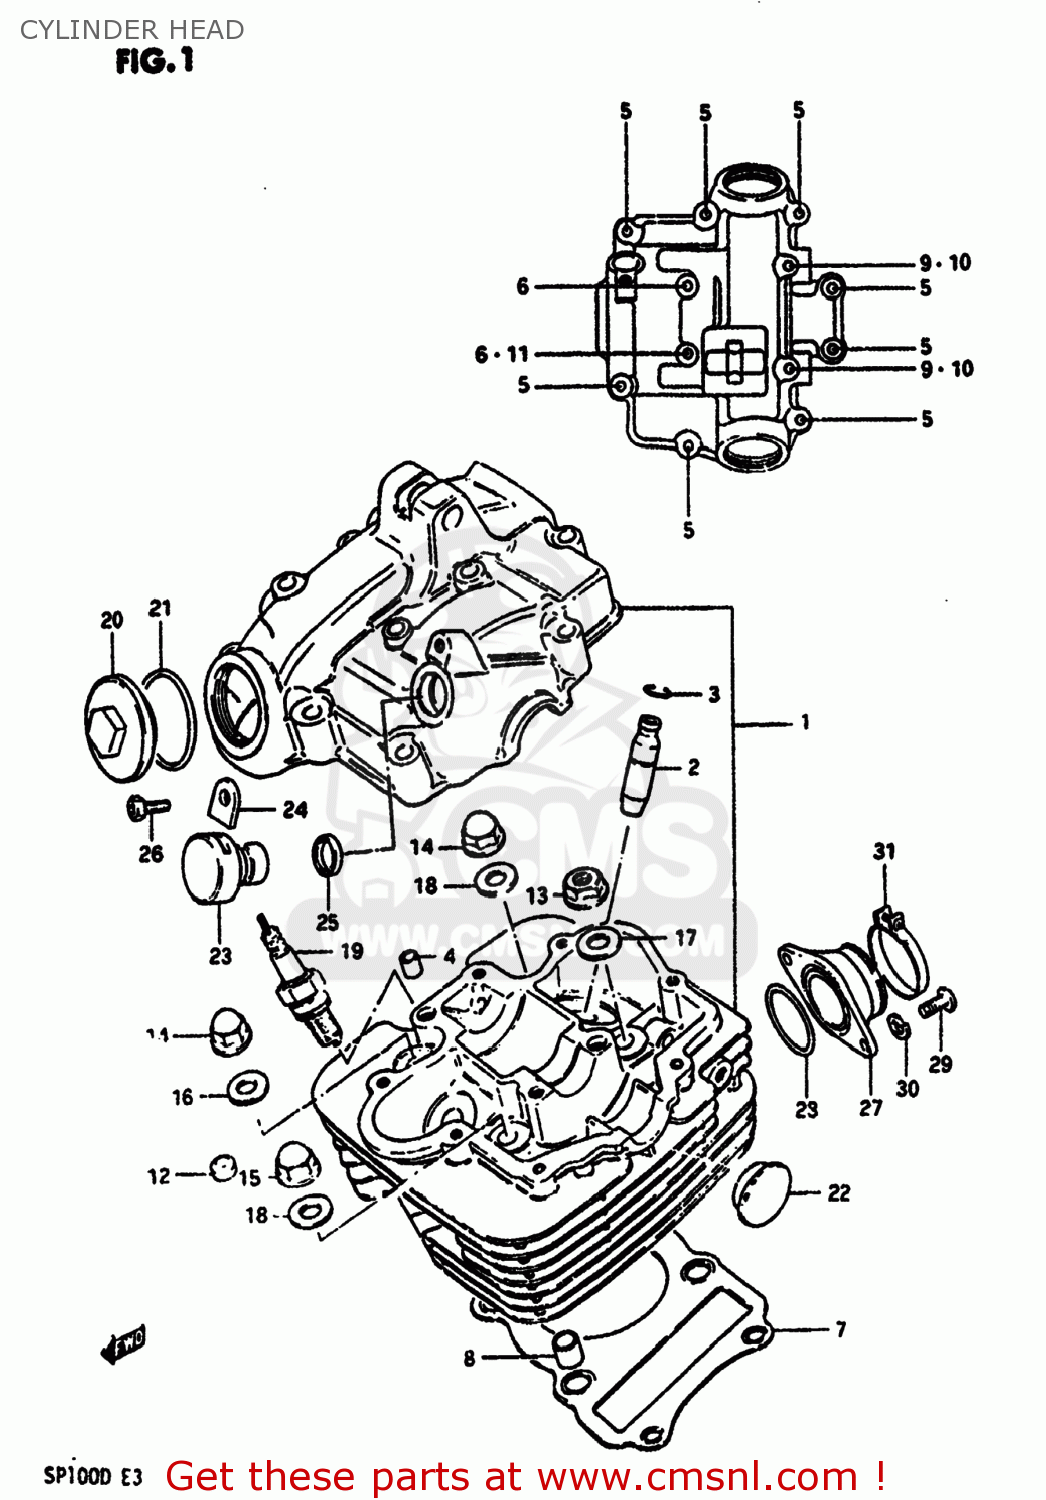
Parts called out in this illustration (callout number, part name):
1	HEAD ASSEMBLY,CYLINDER
2	GUIDE,VALVE
3	RING,SNAP
4	PIN
5	BOLT
6	BOLT ,6X60
7	GASKET,CYLINDER HEAD
8	PIN
9	STUD 6X25
10	NUT
11	GASKET(6.2X11X1).2 (NAS)
12	PAD,CYLINDER HEAD
13	NUT
14	NUT (8MM)
15	NUT
16	WASHER (8.5X19X2.3)
17	WASHER(8.5X19X2.3)
18	GASKET (NAS)
19	SPARK PLUG D8EA
20	CAP,INSPECTION
21	O RING(D:3,ID:29.5)
22	PLUG(OD:22.5)
23	PLUG,TACH GEAR SLEEVE HOLE
24	PLATE,TACH DRIVE GEAR SLEEVE
25	SEAL,TACHOMETER DRIVEN
26	SCREW(5X12)
27	PIPE,INTAKE
28	O RING(D:2.4,ID:31.7)
29	SCREW
30	LOCK WASHER
31	CLAMP
